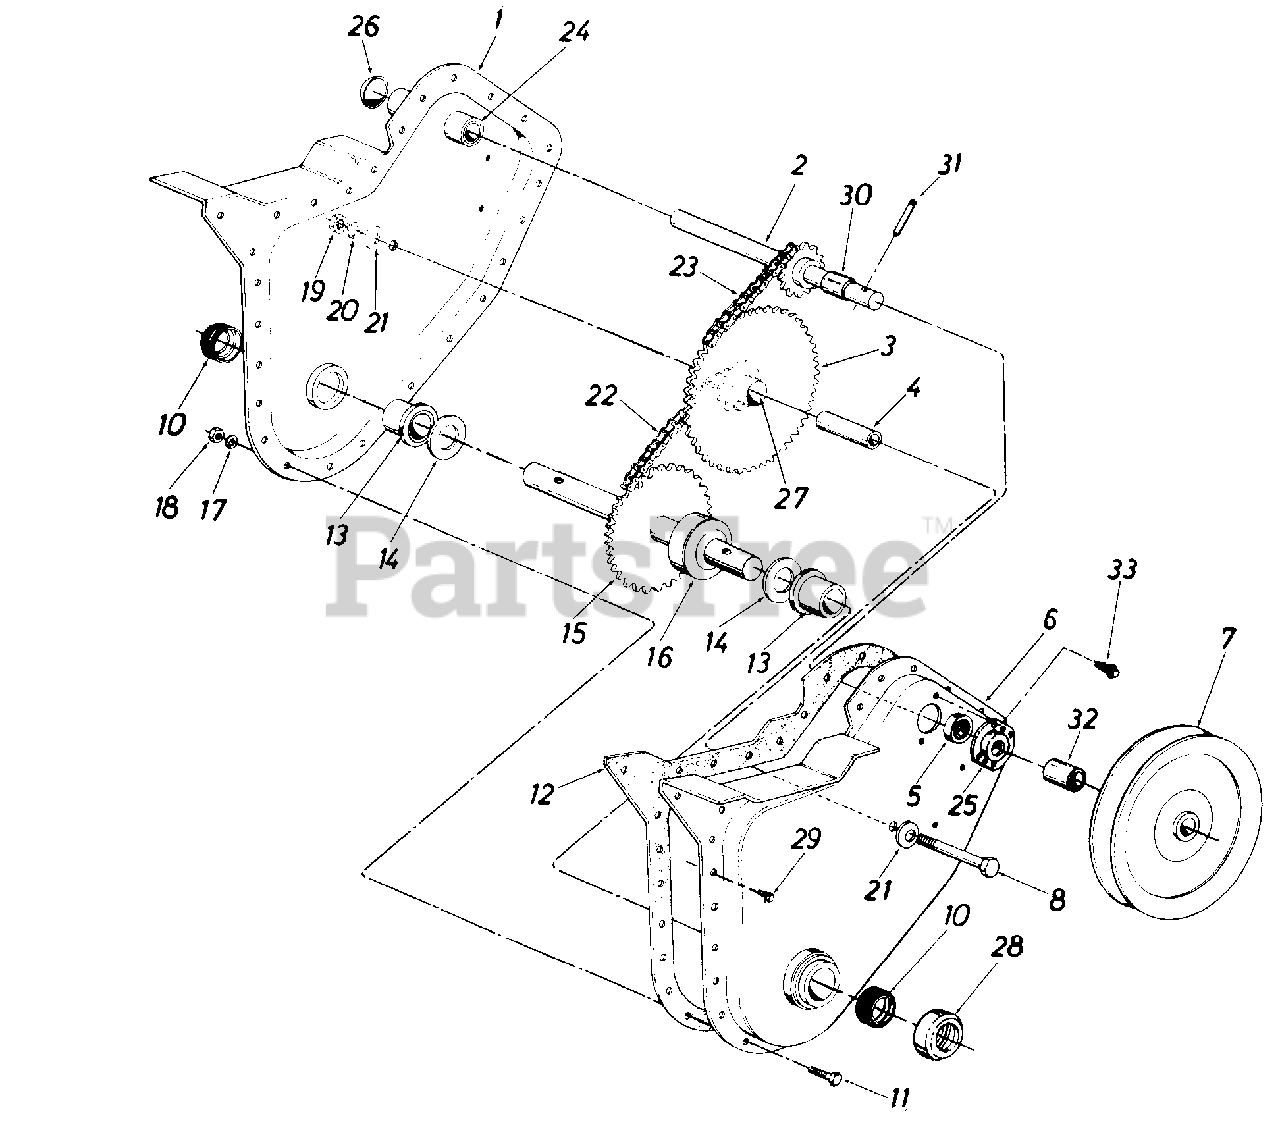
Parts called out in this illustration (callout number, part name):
1	Chain Case Ass'y.-R.H.
2	Input Shaft Ass'y.
3	Hub and Sprocket Ass'y.
4	Bearing Inner Race
5	Ball Bearing
6	Chain Case Ass'y.-L.H.
7	Pulley-Chain Case 5-1/2 x 1/2
8	Hex Bolt 3/8-24 x 2.50" Lg.
11	Hex Bolt 1/4-28 x .625" Lg.
12	Gasket
13	Flange Brg. .879 I.D.
14	Fl-Wash. .88 I.D. x 1.50 O.D. x .030
15	Tine Shaft Ass'y.
16	Spacer 718" I.D. x 2.0" O.D. x.68" Lg.
17	L-Wash. 1/4" Scr.
18	Hex Nut 1/4-28 Thd.
19	Hex Ins. L-Nut 3/8-24 Thd.
20	L-Wash. 3/8" I.D.
21	Bell-Wash. .406 I.D. x 1.130 O.D.
22	Chain #420-.50" Pitch x 38 Links
23	Chain #35-.375" Pitch x 50 Li n ks
24	Bearing .62" I.D. x .813 O.D. x 1.31
25	Bearing Housing
26	Expansion Plug 13/16" Dia.
27	Bearing
28	Dust Cap
29	Hex Wash. Hd. Self-Tap Scr. 1/4-20 x .50" Lg.
30	Spacer .630 I.D. x .77 O.D. x .38" Lg.
31	Spring Pin Spiral 1/4" Dia. x 1-1/2" Lg.
32	Spacer .647 x 1.25"
33	Hex Wash. Hd. Self-Tap Scr. 1/4-20 x .38" Lg.
